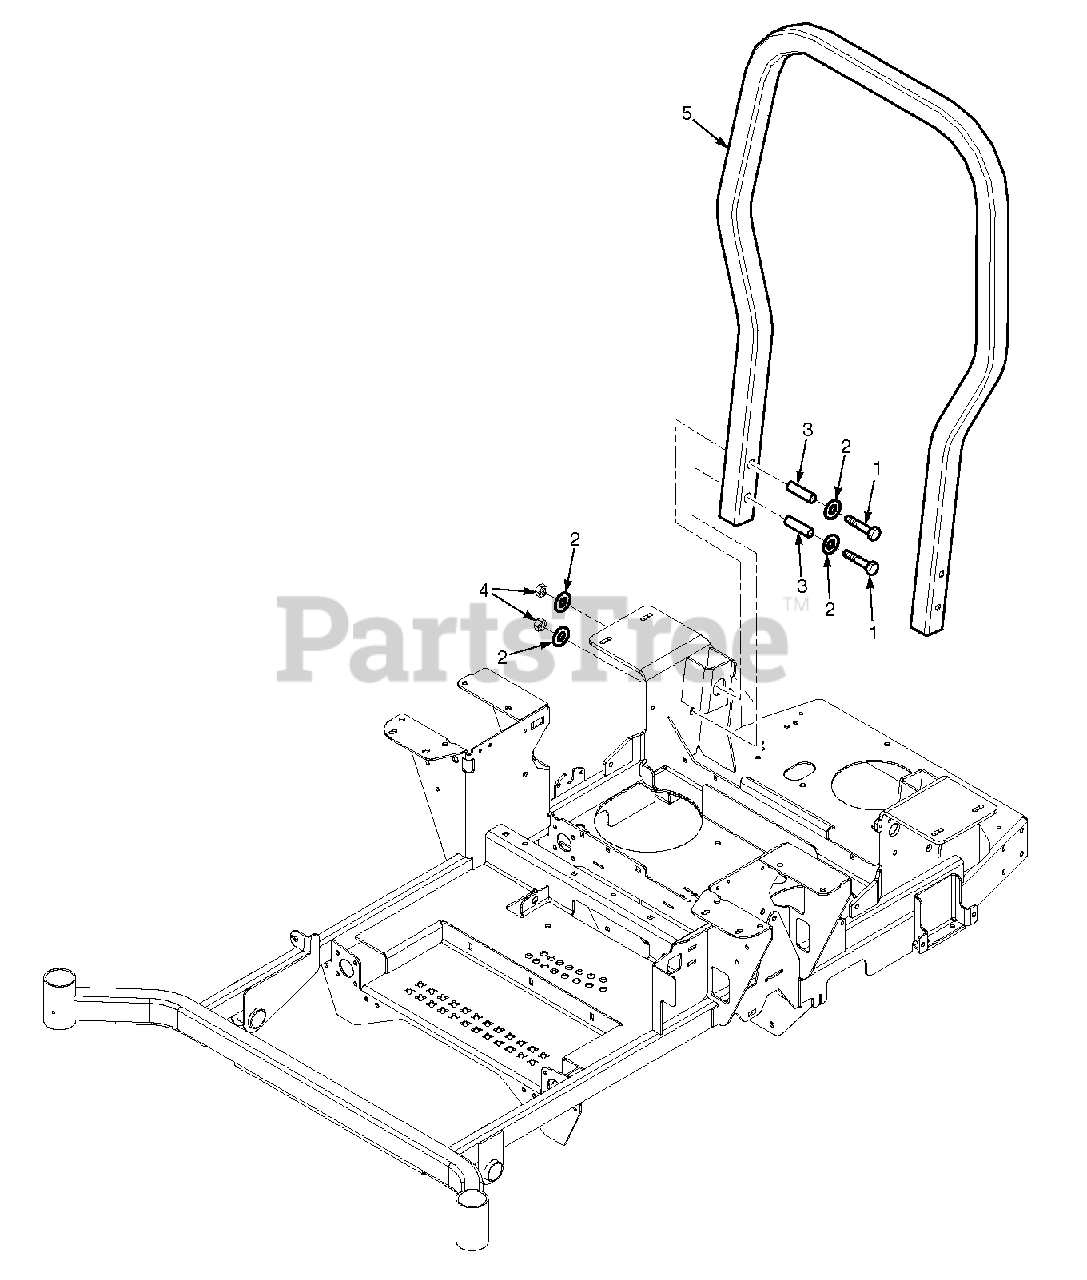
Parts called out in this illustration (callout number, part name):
1	Bolt, Hex Head 1/213 x 3" Gr. 8
2	Flatwasher, 1/2 - .562 x 1.375 x .109
3	Bushing, SFZ ROPS
4	Nut, Center Lock 1/2-13
